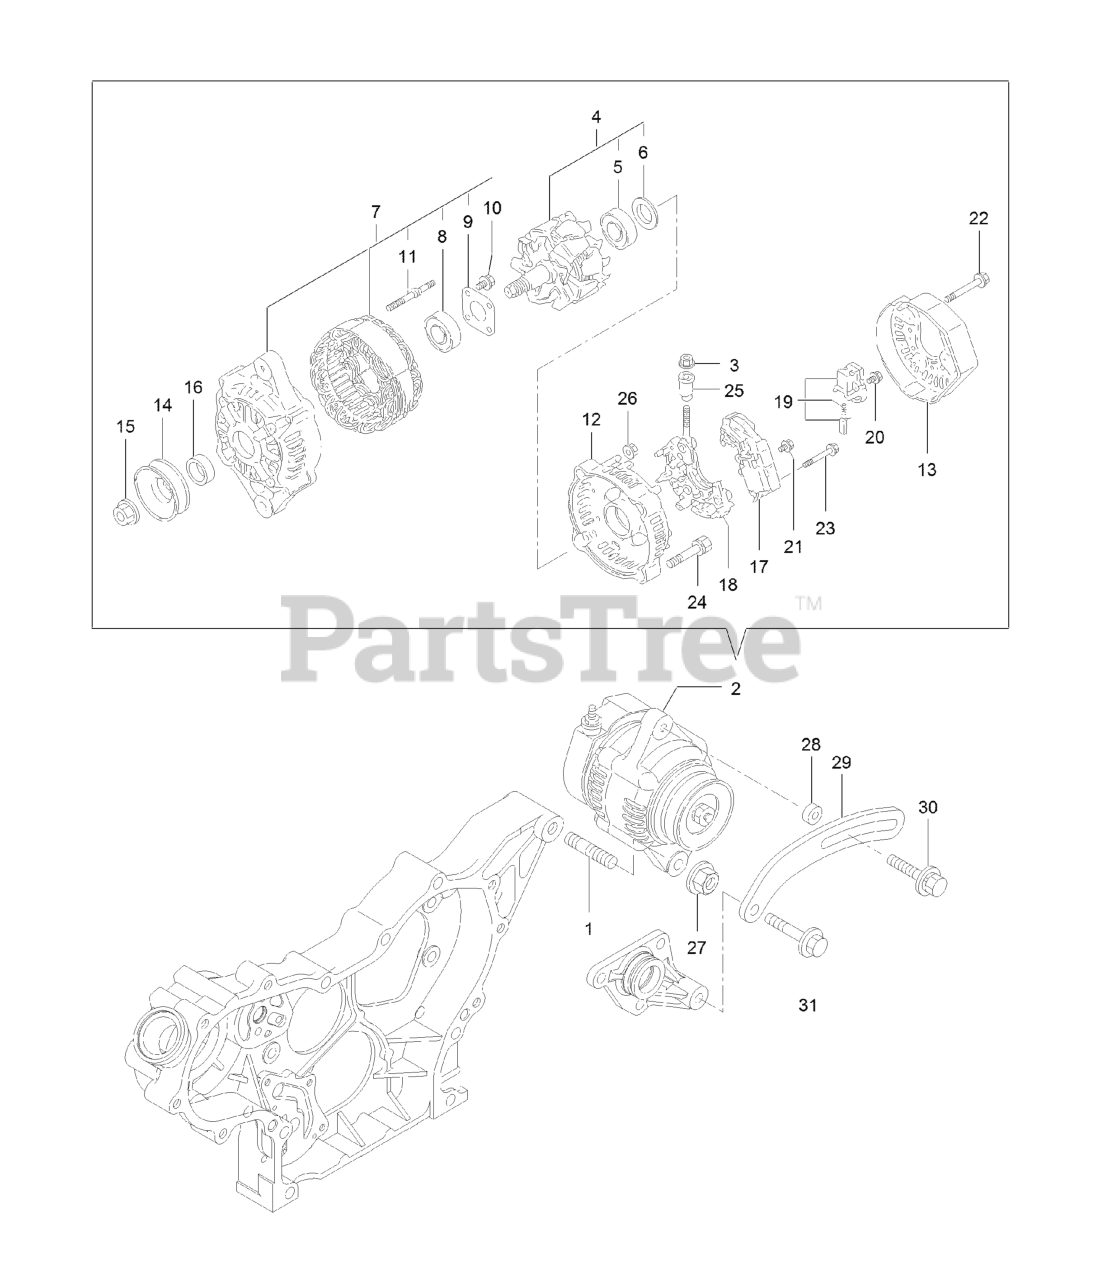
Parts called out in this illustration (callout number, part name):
2	ALTERNATOR
4	Rotor ASM
5	BEARING-BALL
7	FRAME ASM
8	BEARING-BALL
9	Plate-Retainer
17	REGULATOR ASM
25	Bushing-Insulation
29	Adjuster
30	BOLT-ADJUST
